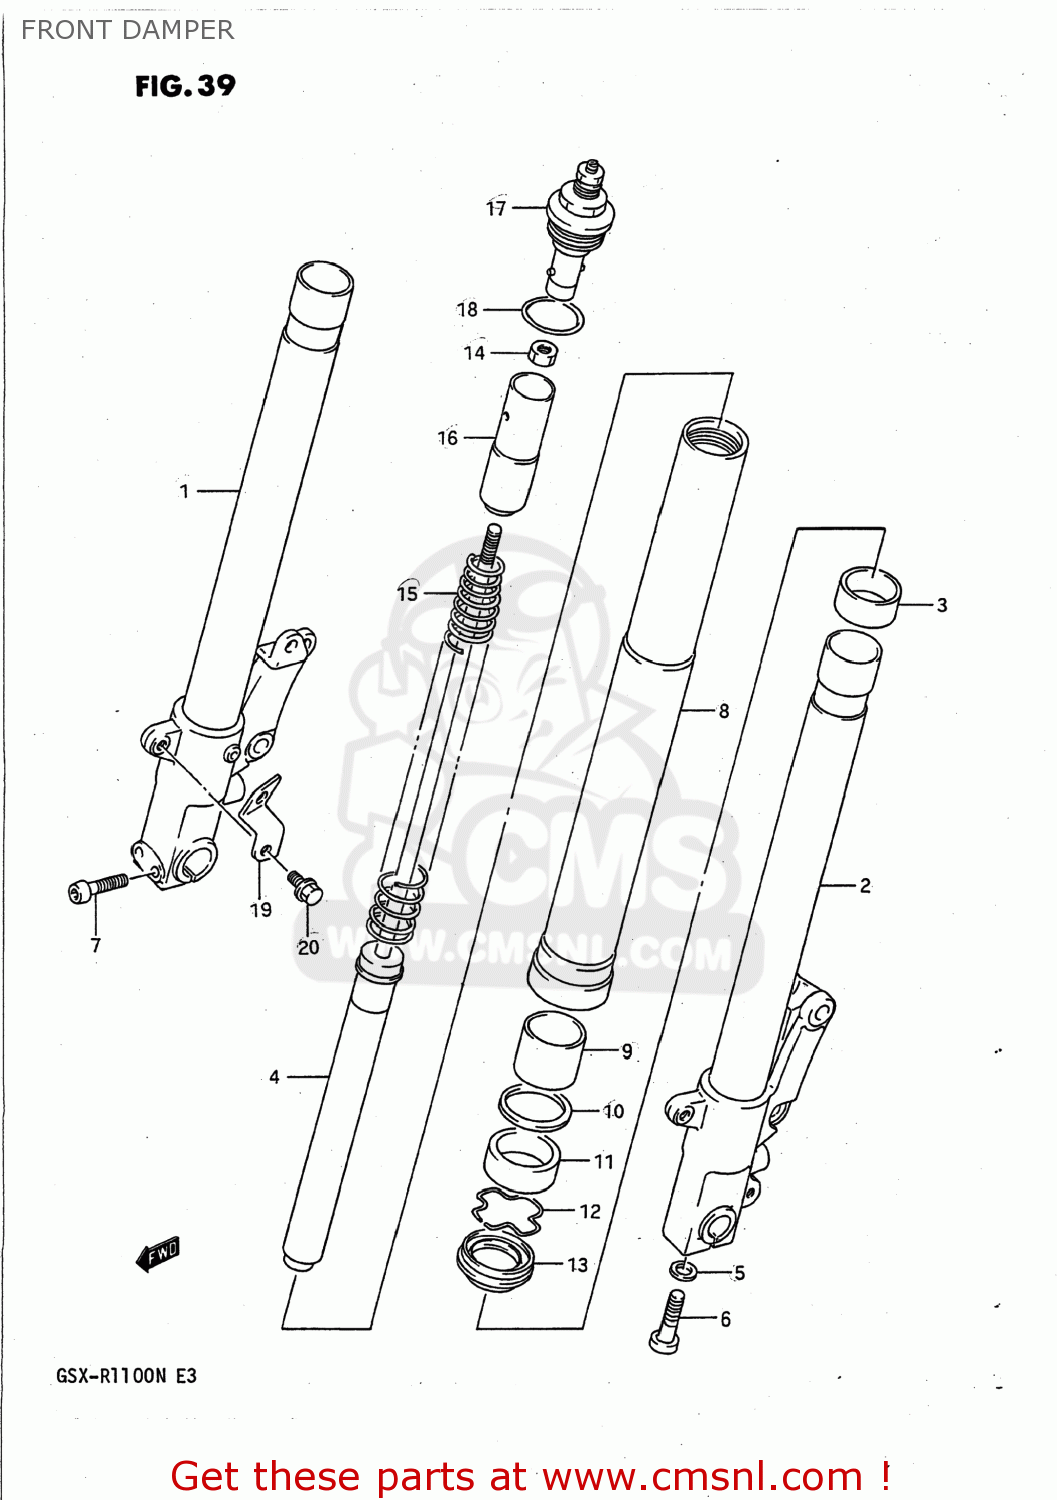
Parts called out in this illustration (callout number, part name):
1	TUBE,INNER,R
2	TUBE,INNER,L
3	PISTON
4	CYLINDER ASSY
5	GASKET,CYLINDER (NAS)
6	BOLT,OIL LOCK PIECE,12X22
7	BOLT
8	TUBE,OUTER
9	10
10	WASHER,FORK OIL SEAL
11	OIL SEAL,FRONT FORK
12	RING,OIL SEAL STOPPER
13	SEAL,DUST
14	NUT,ROD
15	SPRING,MAIN
16	SPACER,SPRING
17	CAP ASSEMBLY,FORK
18	O RING
19	PLATE,FRONT FENDER,LEFT
20	BOLT 8X12
